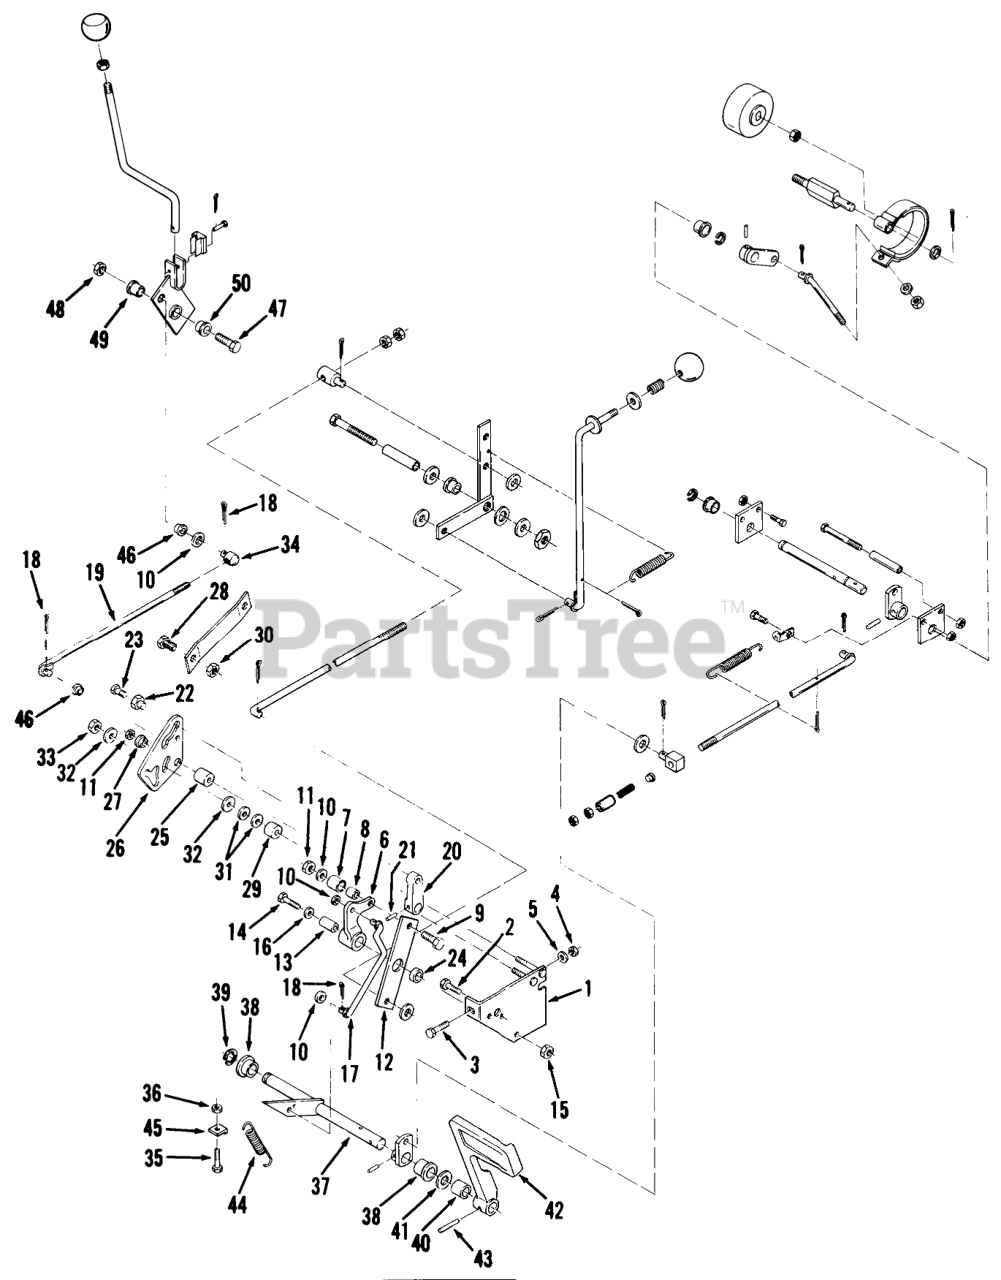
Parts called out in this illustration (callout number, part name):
1	Assy-Plate
2	Screw
3	HHCS
4	Nut
5	WASHER 5/16 SAE
6	Lever-Neutral Return
7	BEARING-CAM RETURN
8	SPACER
9	BOLT
10	Washer
11	Nut
13	Spacer
14	Bolt
15	NUT
16	WASHER
17	Assy-Rod
18	Cotter Pin
20	Arm-Speed Control
21	PIN-ROLL 1/4 X 1 1/4
23	Bolt
24	Spacer
25	SPACER
26	Cam-Speed Control
27	CAM-SPACER
28	Bolt
29	SPACER
30	Nut
31	WASHER-SPRING DISC
32	FRICTION WASHER
33	Nut Conlok 3/8-16
35	Bolt
36	NUT
37	Assy-Shaft
38	BEARING
39	E-RING
40	Spacer
41	WASHER
42	Brake Pedal
43	PIN-ROLL, SPIROL
44	SPRING-EXTENSION
45	CLIP - SPRING
46	BUSHING-FLANGED
47	Bolt
48	NUT
49	CAM-SPACER
50	FLANGED BUSHING
